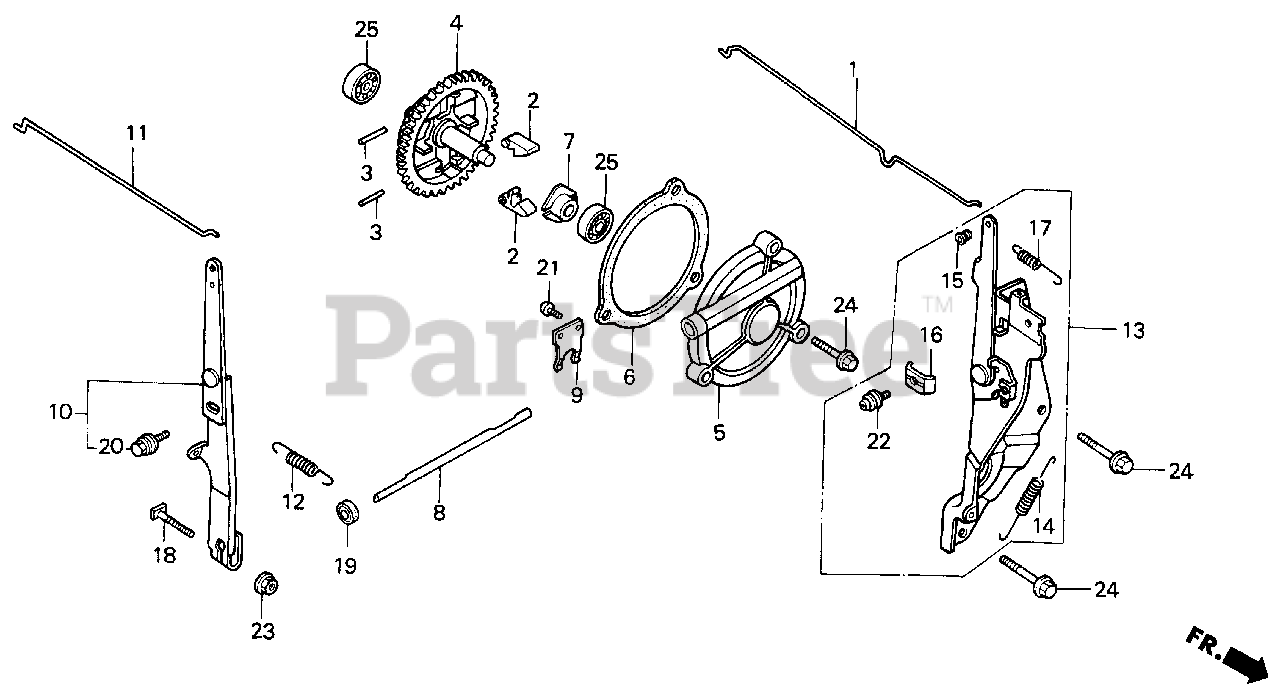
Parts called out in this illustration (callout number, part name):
1	ROD, CHOKE
2	WEIGHT, GOVERNOR
3	PIN, GOVERNOR WEIGHT
4	SHAFT, GOVERNOR
5	COVER, GOVERNOR
6	GASKET, GOVERNOR COVER
7	SLIDER, GOVERNOR
8	SHAFT, GOVERNOR ARM
9	FORK, GOVERNOR
10	ARM, GOVERNOR
11	ROD, GOVERNOR
12	SPRING, GOVERNOR
13	CONTROL
14	SPRING, CONTROL LEVER RETURN
15	COLLAR, LEVER
16	HOLDER, CABLE
17	SPRING, CABLE RETURN
18	BOLT, GOVERNOR ARM
19	OIL SEAL (8X14X5)
20	BOLT-WASHER (6X12)
21	SCREW, PAN (3X8)
22	SCREW-WASHER (5X20)
23	NUT, FLANGE (6MM)
24	BOLT, FLANGE (6X25)
25	BEARING, RADIAL BALL (6000)
